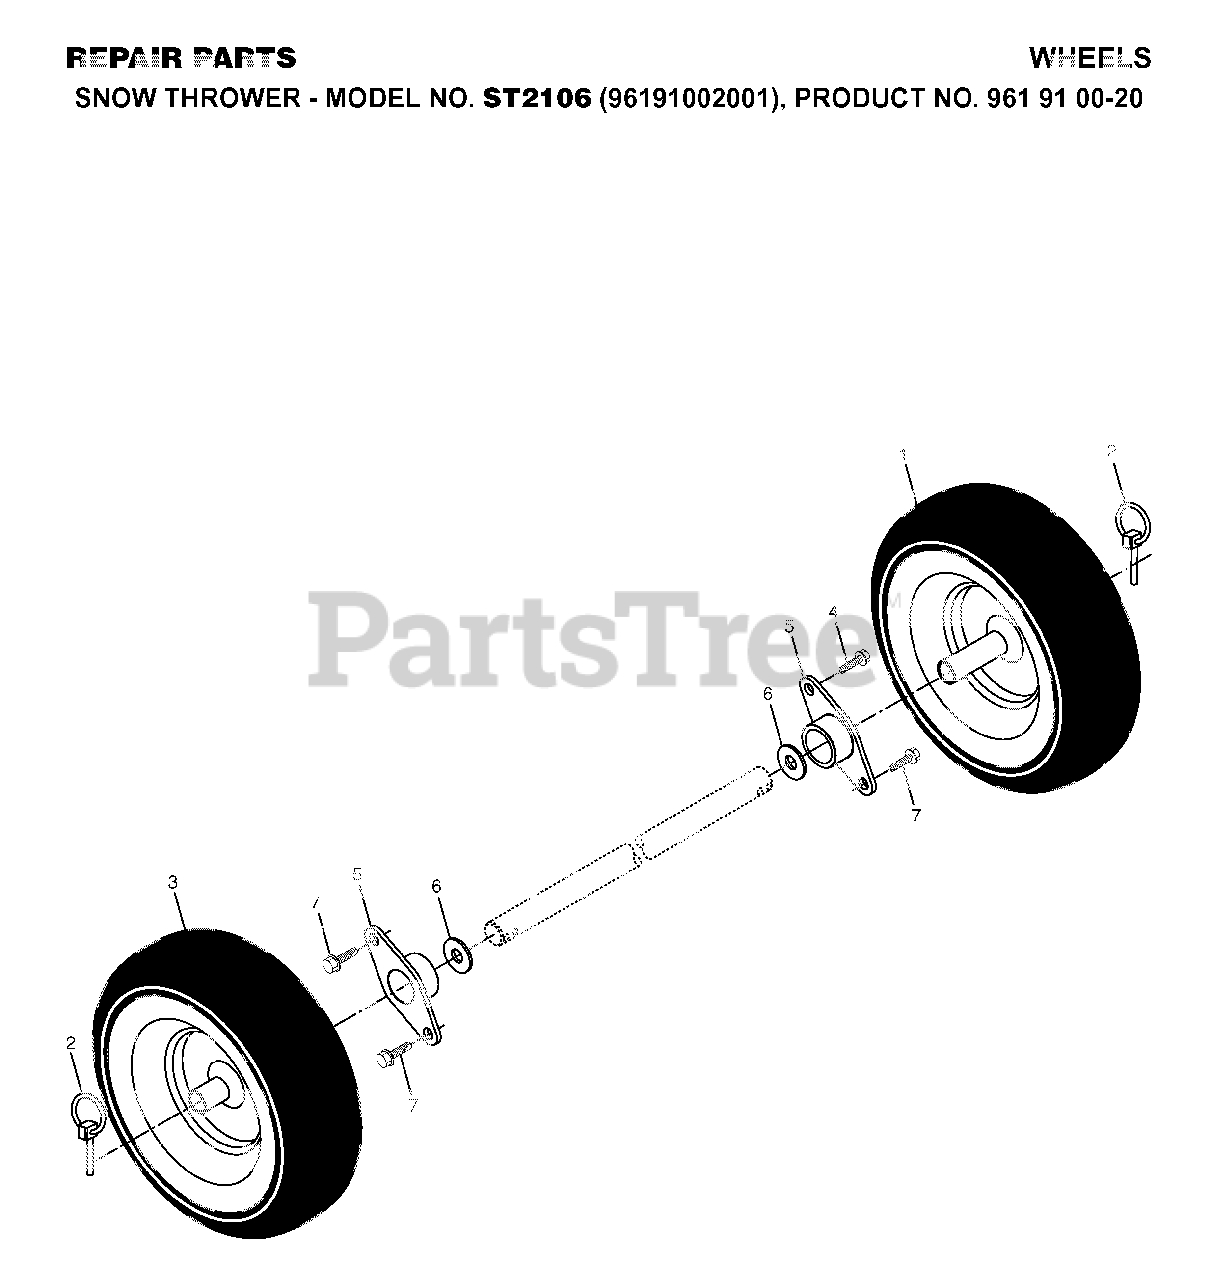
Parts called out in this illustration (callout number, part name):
1	WHEEL.ASM.LT.16"GRY.XTRAC
2	PIN KLIK, 1/4
3	WHEEL.ASM.RT.16".GRAY.XTRAC
5	BEARING, AXLE
6	WASHER TRUST 1"
7	SCREW LT
